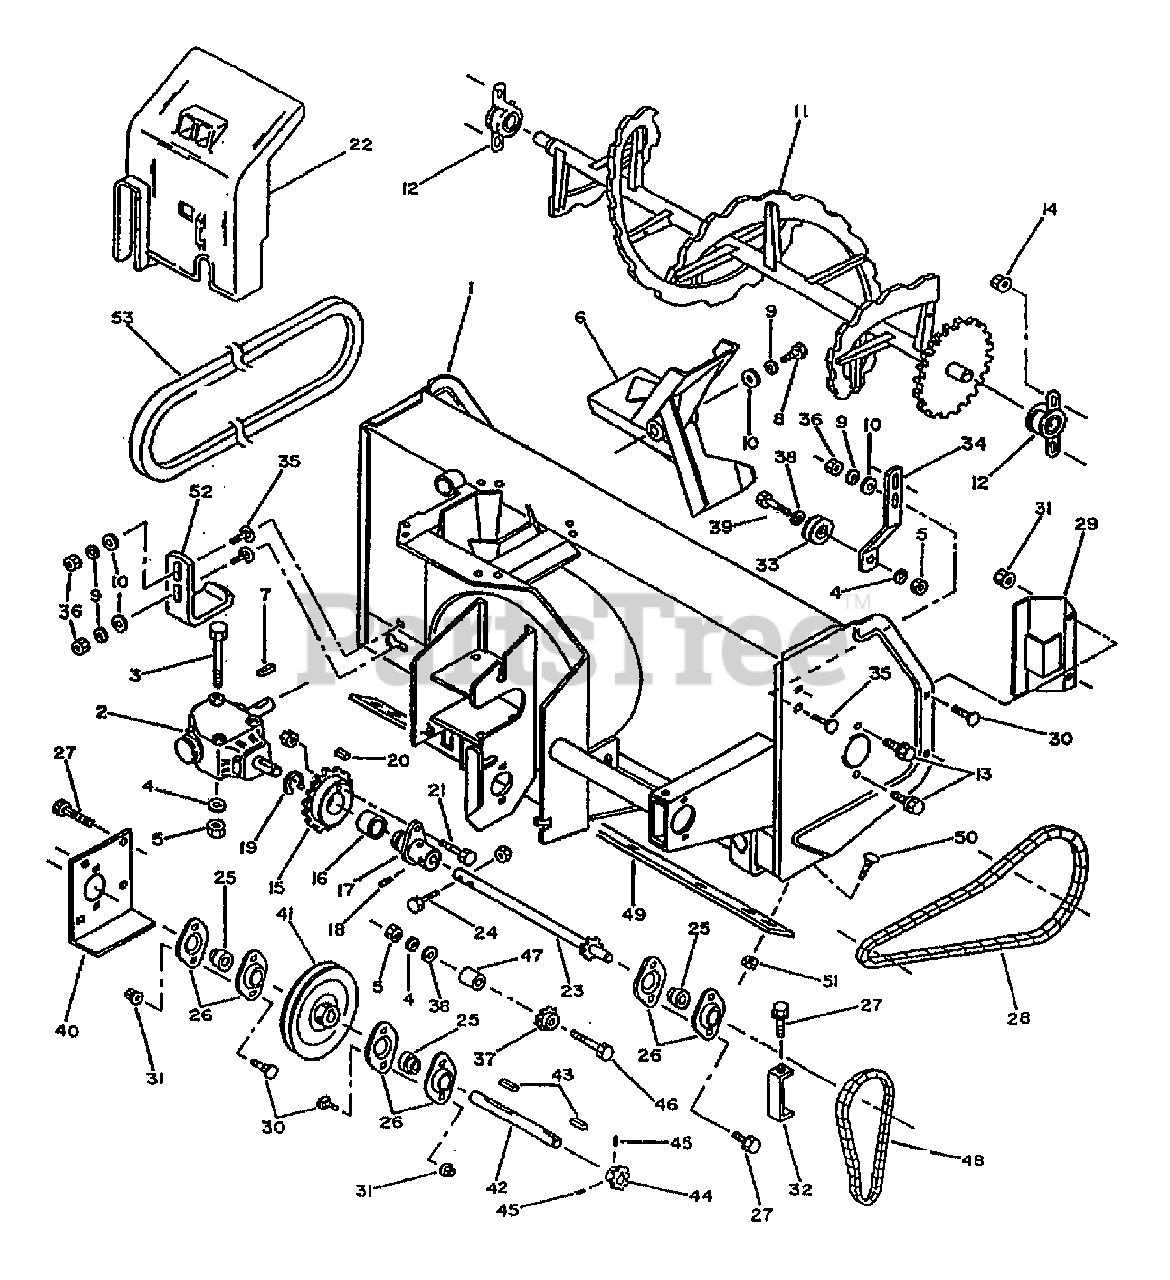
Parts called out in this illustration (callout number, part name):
1	HOUSING-BLOWER
2	ASSM-GEARBOX
3	SCR-HH 3/8-16X4.00
4	WASHER-LK .375 @ DEPL
5	NUT-HEX 3/8-16 ZP
7	KEY-8MM X 7MM X 35MM
8	BOLT-M8X25
9	WASHER-LK .312 ZP
10	WASHER-FLAT 3/8 SAE
11	AUGER-40"
12	BUSHING-SIDEMOUNT
14	NUT-HFLK 3/8-16 ZP
15	SPROCKET
16	BUSHING
17	PLATE-SHEAR
18	SCR-SET
19	RING-SNAP
20	KEY-8 X 8 X 35
21	IMPELLER-SHEAR BOLT
22	COVER
23	SHAFT-DRIVE
24	AUGER-SHEAR BOLT
25	BEARING
26	BEARING-FLANGE
27	SCR-HFLK 5/16-18X.50 ZP
28	CHAIN (#40 91 LINKS)
28	LINK-CONNECTOR
29	GUARD-CHAIN
30	SCR-CARR 5/16-18X.62 G2 ZP
31	NUT-HFLK 5/16-18 ZP
32	GUARD-CHAIN
33	PULLEY-IDLER
34	ARM-ADJUSTER
35	SCR-CARR 5/16-18X1.0 G2 ZP
36	NUT-HEX 5/16-18 ZP
37	SPROCKET-IDLER
38	WASHER-1.25X.5X.083 ZP
39	SCR-HH 3/8-16X1.75 G5 ZP
40	PLATE-BEARING SUPT
41	PULLEY
42	SHAFT-DRIVE
43	KEY-.188 SQ X 1.0
44	SPROCKET (40B10)
45	SCR-SET 1/4-20
46	SCR-HH 3/8-16X2.75 G5 ZP
47	SPACER-IDLER
48	CHAIN-#40 (40 LINKS)
49	EDGE-CUTTING
50	SCR-CARR 5/16-18X.75 G2 ZP
51	NUT-H/LK 5/16-18
52	SHOE-SKID
